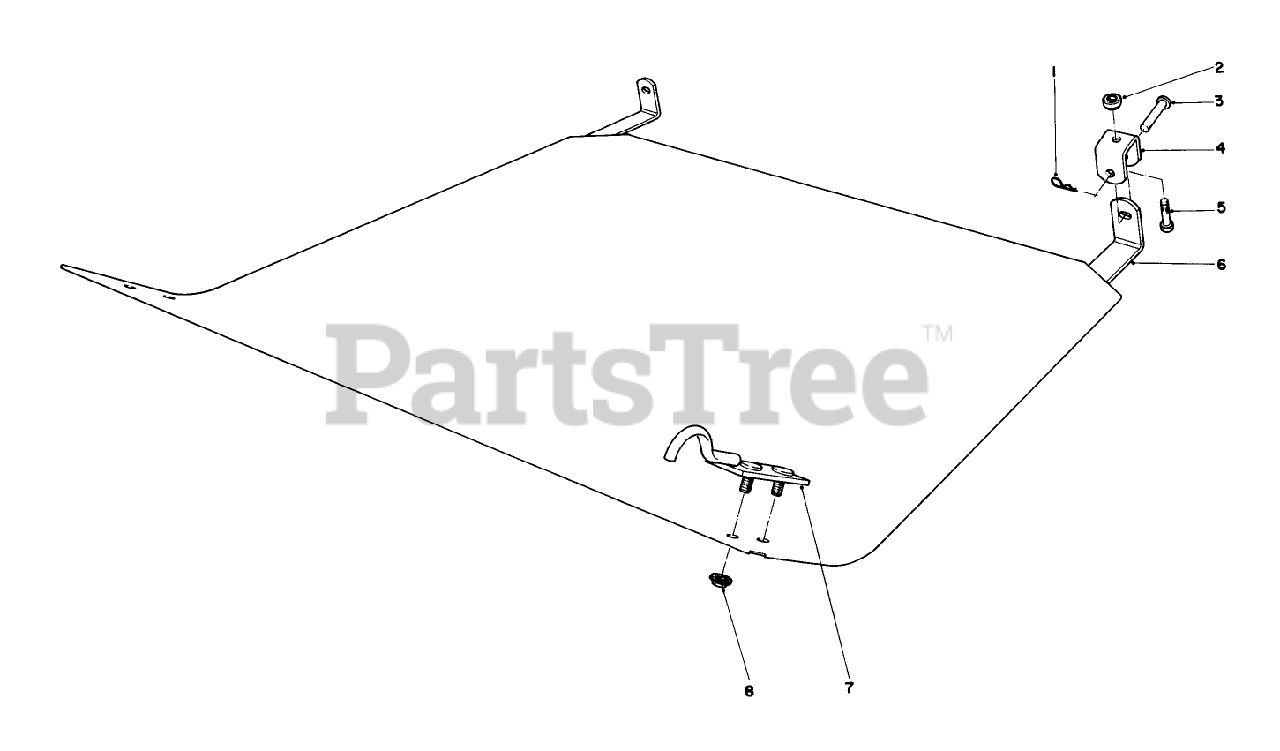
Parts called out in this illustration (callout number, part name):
1	PIN-HAIR
2	SPACER
3	CLEVIS
4	Hanger-Belly Shield
5	SCREW-HH
6	Belly Shield
7	Belly Shield Hook
8	NUT-HF
